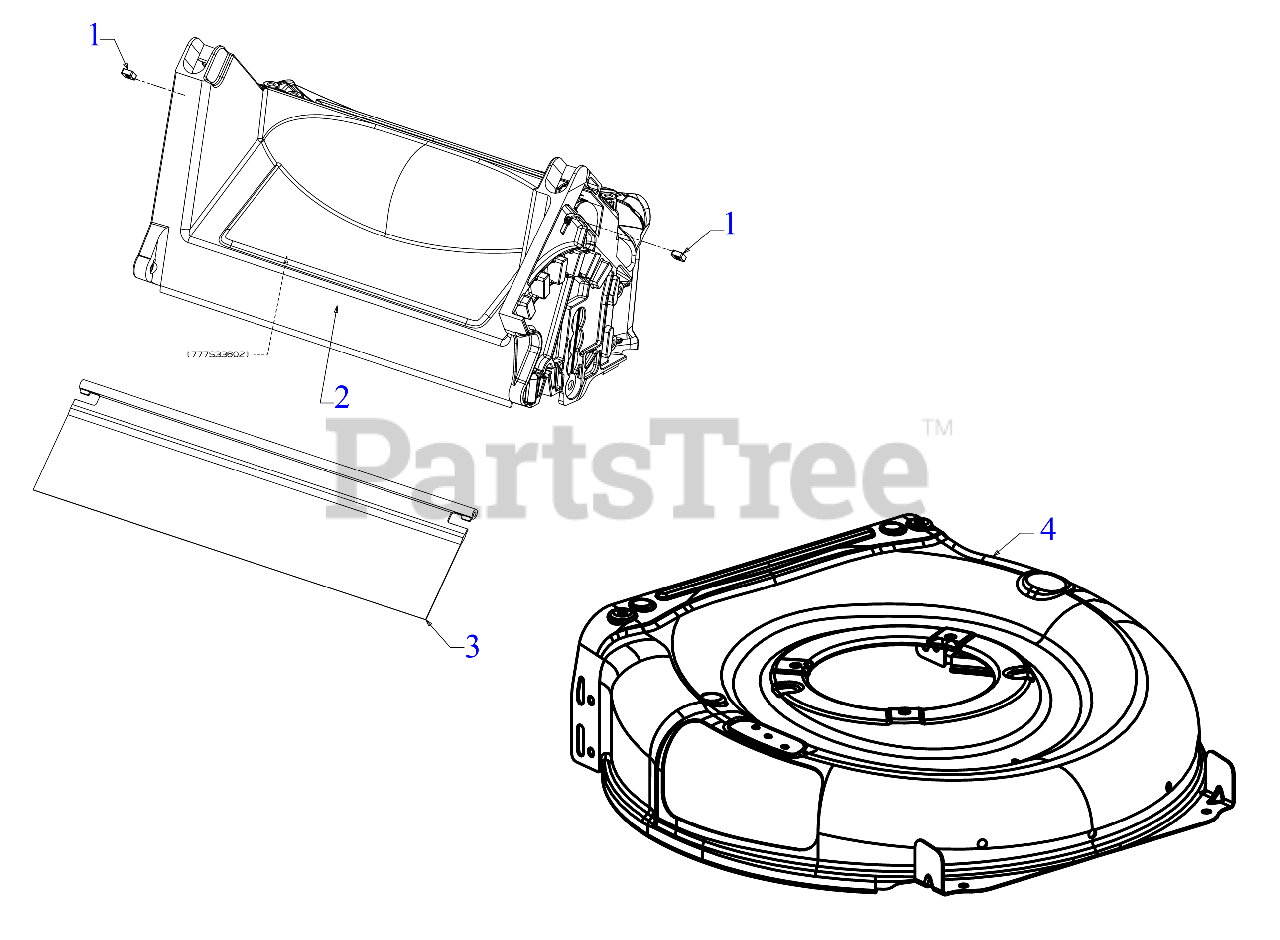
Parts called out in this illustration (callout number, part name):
1	SQUARE NUT 1/4-20
2	REAR BAFFLE ASSEMBLY (2N1)
3	TRAILSHIELD
